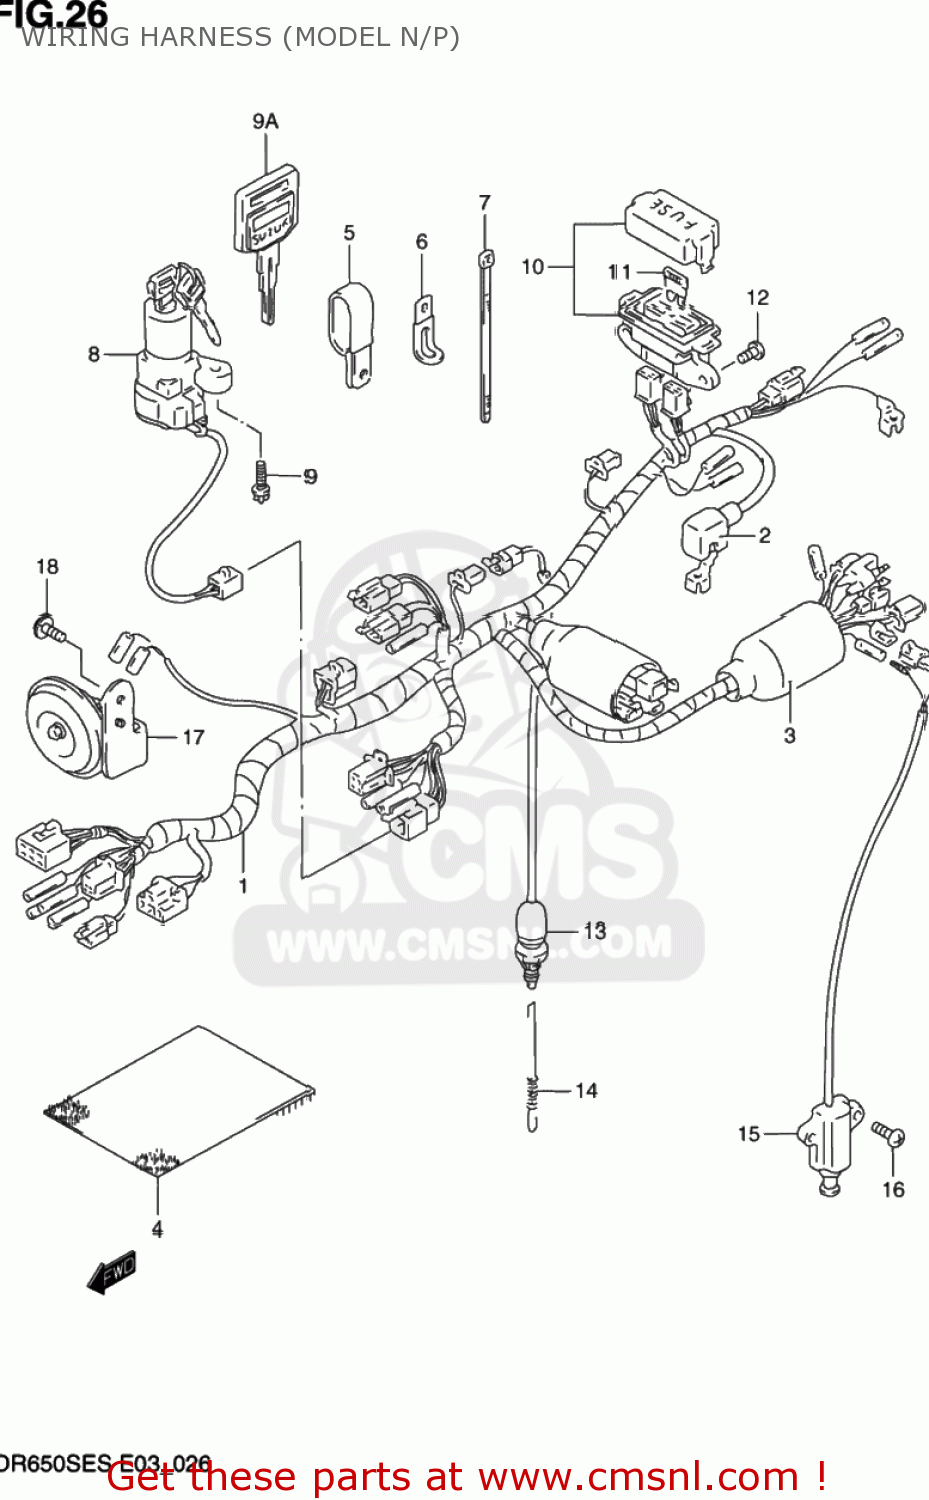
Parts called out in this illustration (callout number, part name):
1	HARNESS,WIRING
2	CAP,BATTERY TERMINAL
3	BOOT,WIRING HARNESS
4	BOOT,WIRING HARNESS
5	CLAMP
6	CLAMP
7	CLAMP
8	LOCK ASSEMBLY,STEERING
9	SCREW(6X18)
9A	KEY,BLANK
10	BOX ASSEMBLY,FUSE
11	FUSE(10A)
12	SCREW
13	SWITCH ASSY,STOP LAMP
14	SPRING
15	SWITCH ASSEMBLY,SIDE STAND
16	SCREW, CENTER
17	HORN ASSEMBLY
18	BOLT, BRACKET (6X12)
